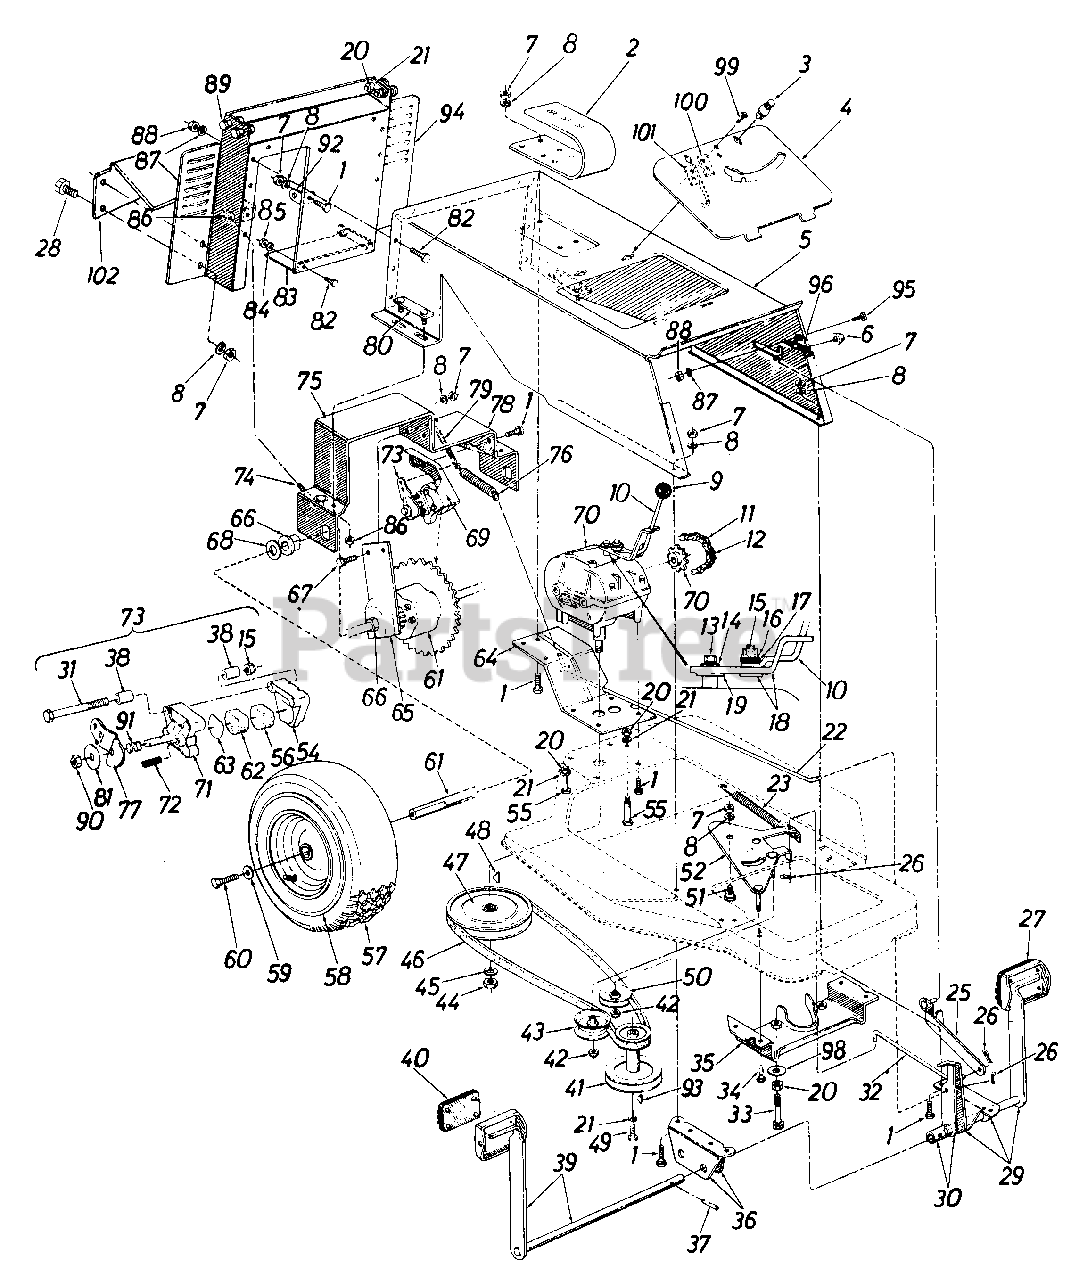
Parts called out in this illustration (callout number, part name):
1	Hex Sems Scr. 5/16-18 x .75" Lg.*
2	Seat Spring 3.25" High
3	Fastener
4	Rear Frame Cover
5	Rear Frame
6	Push Cap .25" Dia.-Black
7	Hex Nut 5/16-18 Thd.
8	L-Wash. 5/16" Scr.
9	Ball Knob
10	Shift Lever-Transmission
11	#420 Chain 1/2" Pitch x 77 Links
12	#420 Master Link
13	Hex Scr. 1/4-28 x .62" Lg.
14	Bell. Wash. .25" I.D. x .88 O.D. x .062
15	Hex Cent. L-Nut 5/16-18 Thd.
16	Fl-Wash. .344 I.D. x .88 O.D.
17	Rubber Wash. .33 I.D. x .87
18	Shift Lever Brkt. Ass'y.
19	Hardened Wash. 1.00 O.D.
20	Hex Nut 3/8-16 Thd.
21	L-Wash. 3/8" Scr.
22	Brake Rod
23	Extension Spring
25	Clutch Lockout Ass'y.
26	Cotter Pin 3/32" Dia. x .75"*
27	Clutch Pedal Pad
28	Hex Bolt 5/16-18 x .75" Lg.
29	Clutch Pedal & Brkt. Ass'y.
30	Brake Lever Ass'y.
31	Hex Scr. 5/16-18 x 2.50" Lg.
32	Clutch Rod
33	Hex Scr. 3/8-16 x 3.5" Lg.
34	Hex Sems Scr. 1/4-20 x .75"
35	Engine Belt Guard Ass'y.
36	Pedal "U" Brkt.-R.H.
37	Spring Pin Spiral .25" Dia. x 1.50" Lg.
38	Bushing
39	Brake Pedal Shaft Ass'y.
40	Brake Pedal Pad
41	Two-Step Engine Pulley
42	Hex Ins. L-Nut 3/8-24 Thd.
43	Fl-Idler w/Flanges 2.75" Dia.
44	Hex Jam Nut 1/2-20 Thd.
45	L-Wash. 1/2" Scr.
46	"V"-Belt 1/2" x 62" Lg.
47	Transmission Split Pulley .50" I.D.
48	#4 Hi-Pro Key 3/32 x 518" Dia.
49	Hex Scr. 3/8-24 x .75" Lg.
50	"V"-ld ler
51	Shld. Scr. .437" Dia. x .180
52	Idler Brkt. Ass'y.
54	Casting-Carrier
55	Shld. Scr. .498" Dia. x 2.00"
56	Pad-Friction
57	Rear Wheel Ass'y.-Comp. 14.5 x 4.5
58	Rear Wheel Rim Only
59	Bell. Wash. .345 I.D. x .88
60	Hex Cent. Lock Scr. 5/16-24 x .75" Lg. H.T.
61	Differential Ass'y. Comp.
62	Pad-Friction
63	Disc-Back-Up
64	Seat Support Ass'y.
65	Rear Axle Plate
66	Flange Brg. w/Flats .753 I.D.
67	Hex Sems Scr. 5/16-18 x 1.00" Lg.*
68	Fl-Wash. .812 I.D. x 1.38" O.D. x .100
69	Disc Brake Brkt. Ass'y.
70	Transmission (Five Speed)
71	Casting-Cam
72	Push Pin
73	Disc Brake Ass'y.-Comp.
74	Chain Adj. Link 5/16-18 x 4.38" Lg.
75	Rear Axle Brkt.-R.H.
76	Brake Spring
77	Cam Lever
78	Rear Axle Brkt.-L.H.
79	Brake Return Spring
80	Plate Ass'y. Axle Bolt
81	Washer
82	Truss Hd. Mach. Scr. 10-24 x.62" Lg.
83	Baffle Plate
84	Ext. L-Wash.
85	Hex Nut 10-24 Thd.*
86	Hex Ins. L-Nut 5/16-18 Thd.
87	L-Wash. 1/4" Scr.
88	Hex Nut 1/4-20 Thd.*
89	Shld. Scr. .498 Dia. x .330
90	Hex Top L-Nut
92	Chute Pivot Brkt.
93	#6 Hi-Pro Key 5/32 x 5/8" Dia.
94	Grass Catcher Adapter
95	Hex Scr. 1/4-20 x .50" Lg.
96	Safety Switch
98	Belleville Washer
99	Hex Wash. Hd. Scr. #8 x .50"
100	Insulator Nut Plate
101	Spring Switch
102	Rear Chute Baffle
